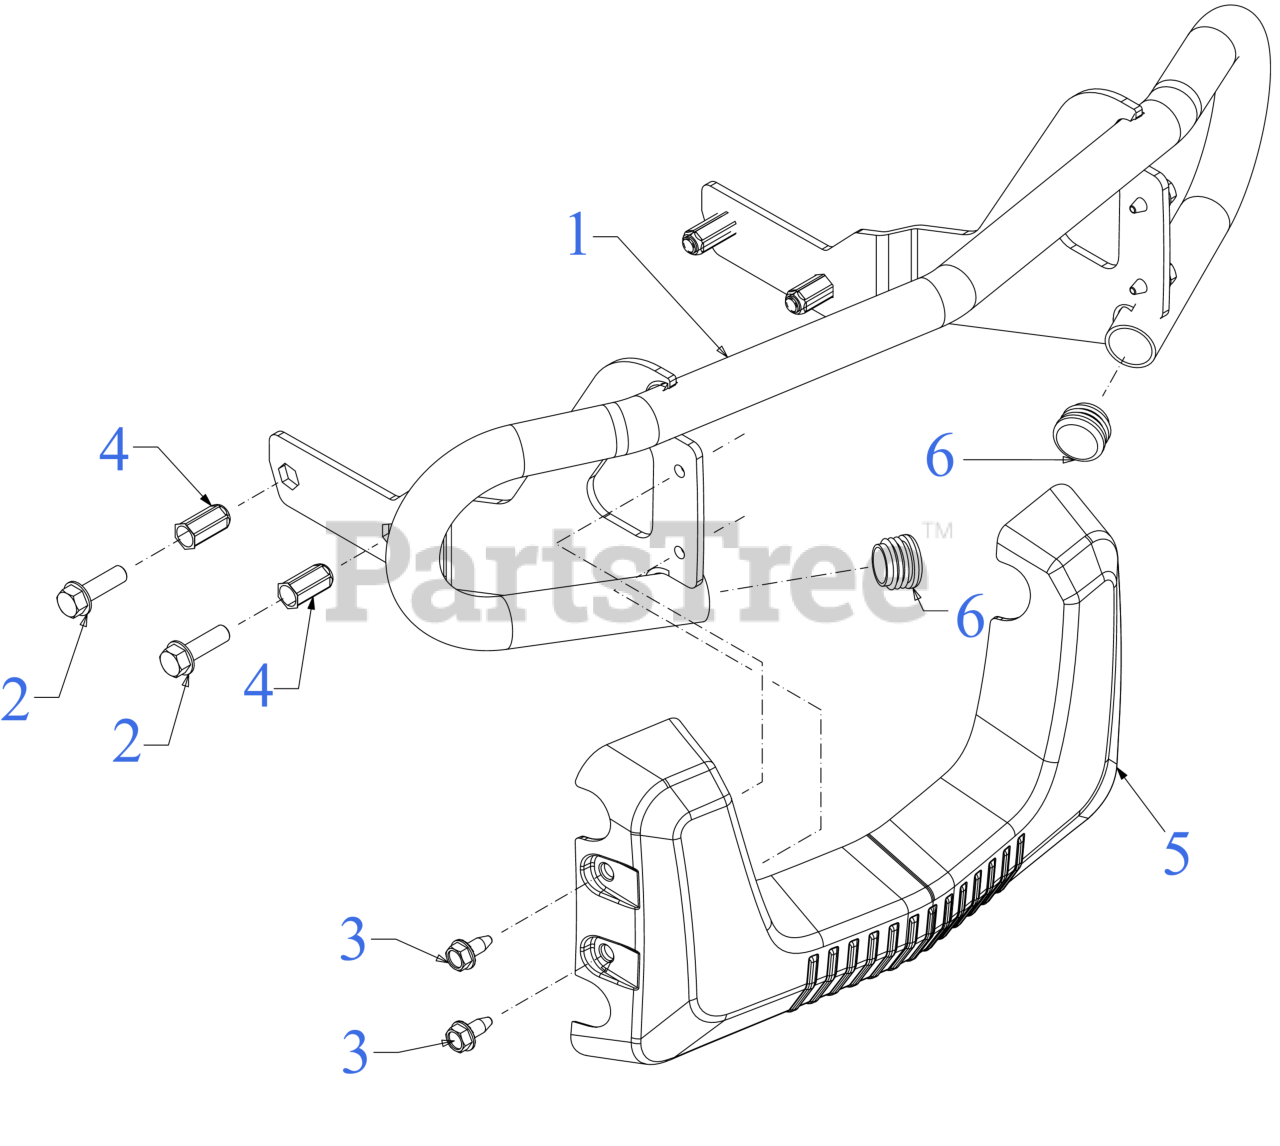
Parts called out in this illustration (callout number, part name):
1	BUMPER
2	SCREW 3/8-16 x 1.25 GR5
3	SCREW M8-1.25 x .750
4	NUT RIVET 3/8-16
5	BUMPER COVER
6	BUMPER TUBE CAP
